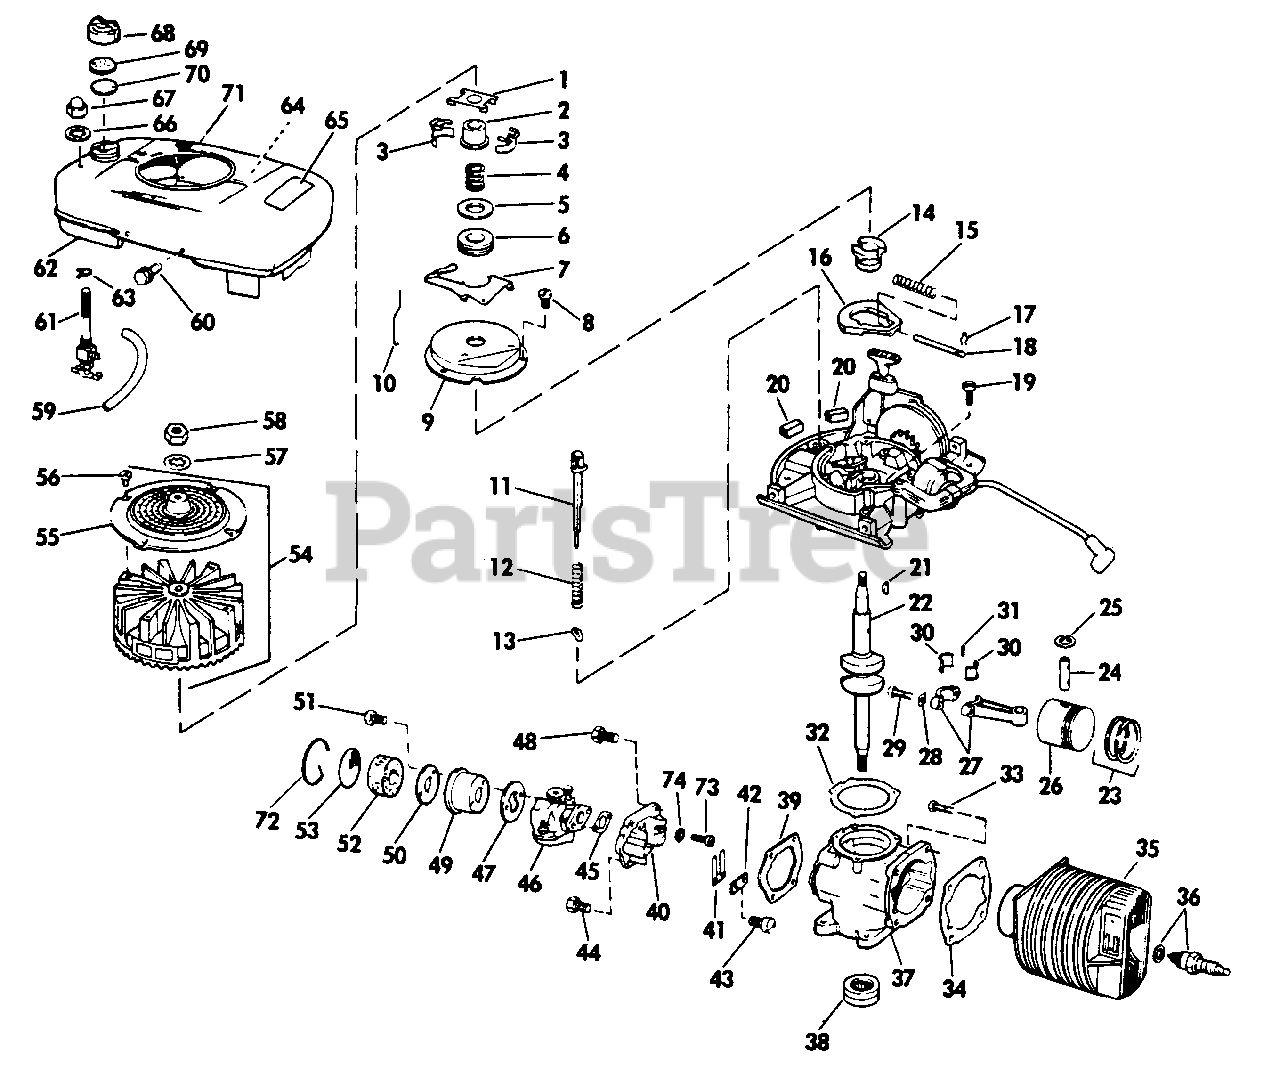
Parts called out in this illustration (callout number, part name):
1	Yoke-Governor
2	Collar-Governor
3	Weight-Governor
4	Spring-Governor
5	Thrust Washer
6	Collar-Thrust
7	Lever-Governor
8	Screw-Attaching Dust Cover
9	Dust Cover
10	Rod-Governor
11	Bar-Shut-Off and Primer
12	Spring-Shut-Off Switch
13	Blade-Switch
14	Cam-Spark Advance
15	Spring-Spark Advance
16	Flyweight-Spark Advance
17	Retainer-Spring
18	Pin-Spark Advance
19	Screw-Arm. Plate to Crankcase
20	Pad-Rubber, Arm. Plate
21	Key-Crankshaft
22	Crankshaft
23	Ring Set (2 Rings)
24	Wrist Pin
25	Retaining Ring-Wrist Pin
27	Connecting Rod Assy.
28	Lockplate
30	Liners-Connecting Rod (Set)
31	Needle Set
32	Gasket-Crkc. to Arm. Pl. .005 in.
32	Gasket-Crkc. to Arm. Pl. .010 in.
33	Screw-Machine, Cyl. to Crkc.
34	Gasket-Cyl. to Crankcase
35	Cylinder and Sleeve Assy.
36	Spark Plug and Gasket
37	Crankcase and Seal Assy.
38	Oil Seal
39	Gasket-Reed Plate
40	Reed Plate Assembly
42	Plate-Back-Up
43	Screw-Machine
44	Scr.-Reed Pl. to Crkc.
45	Gasket-Carburetor
46	Carburetor Assembly
48	Scr.-Reed Pl. to Crkc.
49	Cup-Air Filter
50	Plate Back-Up
51	Screw-Filter to Carburetor
52	Element-Air Filter
53	Screen-Air Filter
54	Flywheel and Screen Assy.
55	Screen and Cup
57	Lockwasher-Flywheel
58	Nut-Flywheel
59	Gas Line
60	Screw-Shroud to Armature Plate
61	Shut-Off Valve
62	Gas Tank Assy.
64	Decal-LAWN-BOY
65	Decal-Instruction
66	Lockwasher
71	Shroud and Shield Assy.
72	Clip-Air Filter
